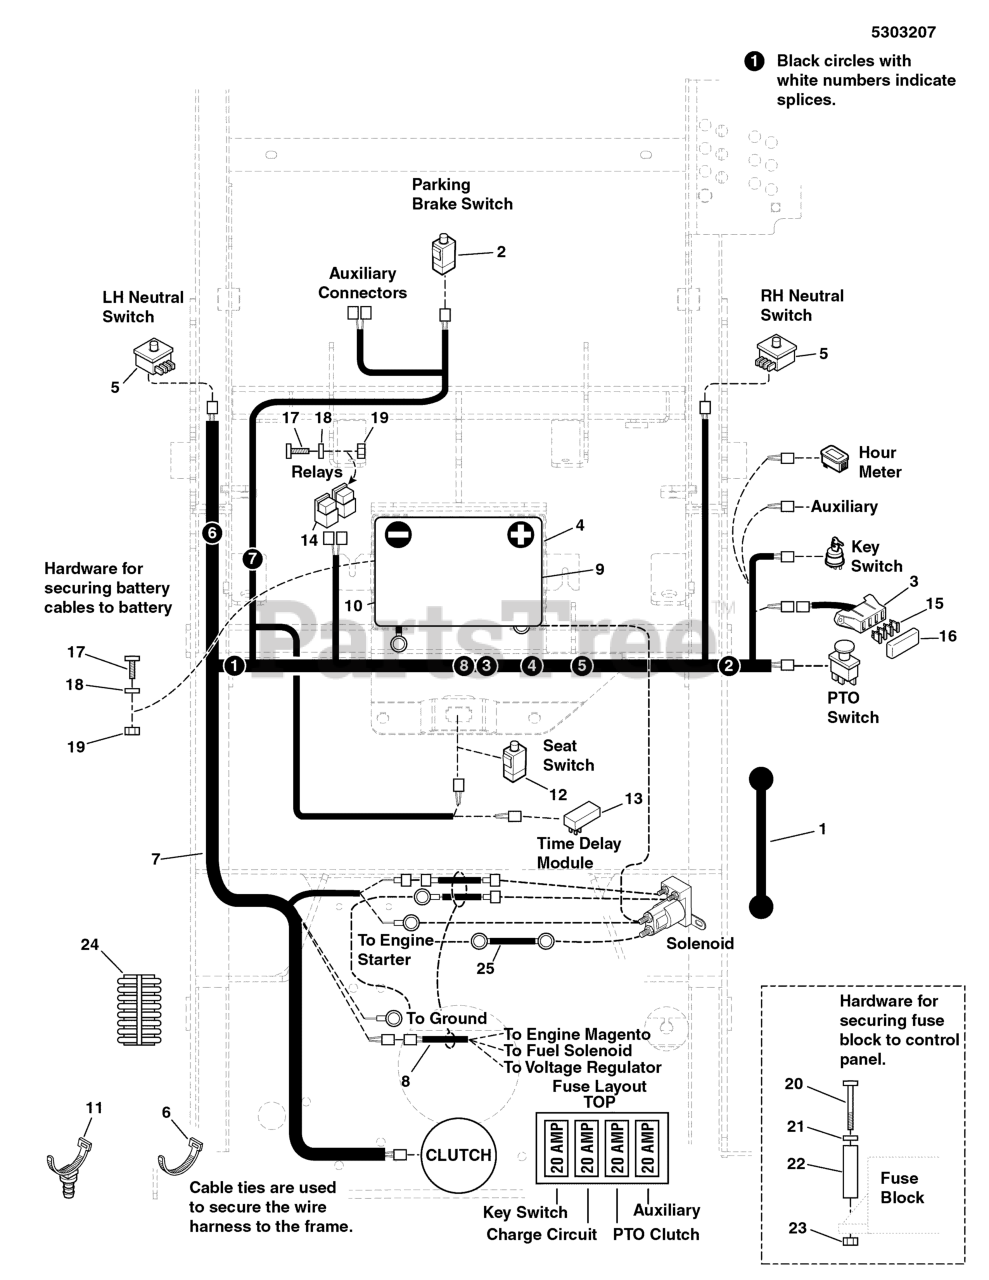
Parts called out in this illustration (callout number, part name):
1	STRAP-BLACK RUBB
2	SWITCH, DP NO/NC SNAP-IN
3	WIRE HARNESS, FUSE BLOCK - IS2000
5	SWITCH, LOW PROF, NC/NO
6	CABLE TIE, 12
7	WIRE HARNESS, MAIN, S150XT
8	WIRE HARNESS, BRIGGS JUMPER
9	BATTERY CABLE, POSITIVE, 35
10	BATTERY CABLE, NEGATIVE, 35
11	CABLE TIE FIR TREE MOUNT, WAYTEK 21374
12	SWITCH, PLUNGER, NO/NO SNAP-IN
13	MODULE, TIME DELAY
14	RELAY, 12V, 40A
15	FUSE, 20 AMP, ATO
16	COVER, VINYL FUSE BLOCK
17	BOLT, 1/4-20 X 3/4 GD5 YZ
18	WASHER, 1/4 SAE
19	NUT, 1/4-20 HEX SERR. FLANGE
20	SCREW, #10-24 X 2 ROUND PHILLIPS
21	NUT, #10-24 HEX NYLON LOCK
22	WASHER, #10 SAE
23	SPACER, .20 X .38 X 1.25
24	WIRE LOOM, 3/8 ID X 15 IN
25	BATTERY CABLE, POSITIVE, 8
